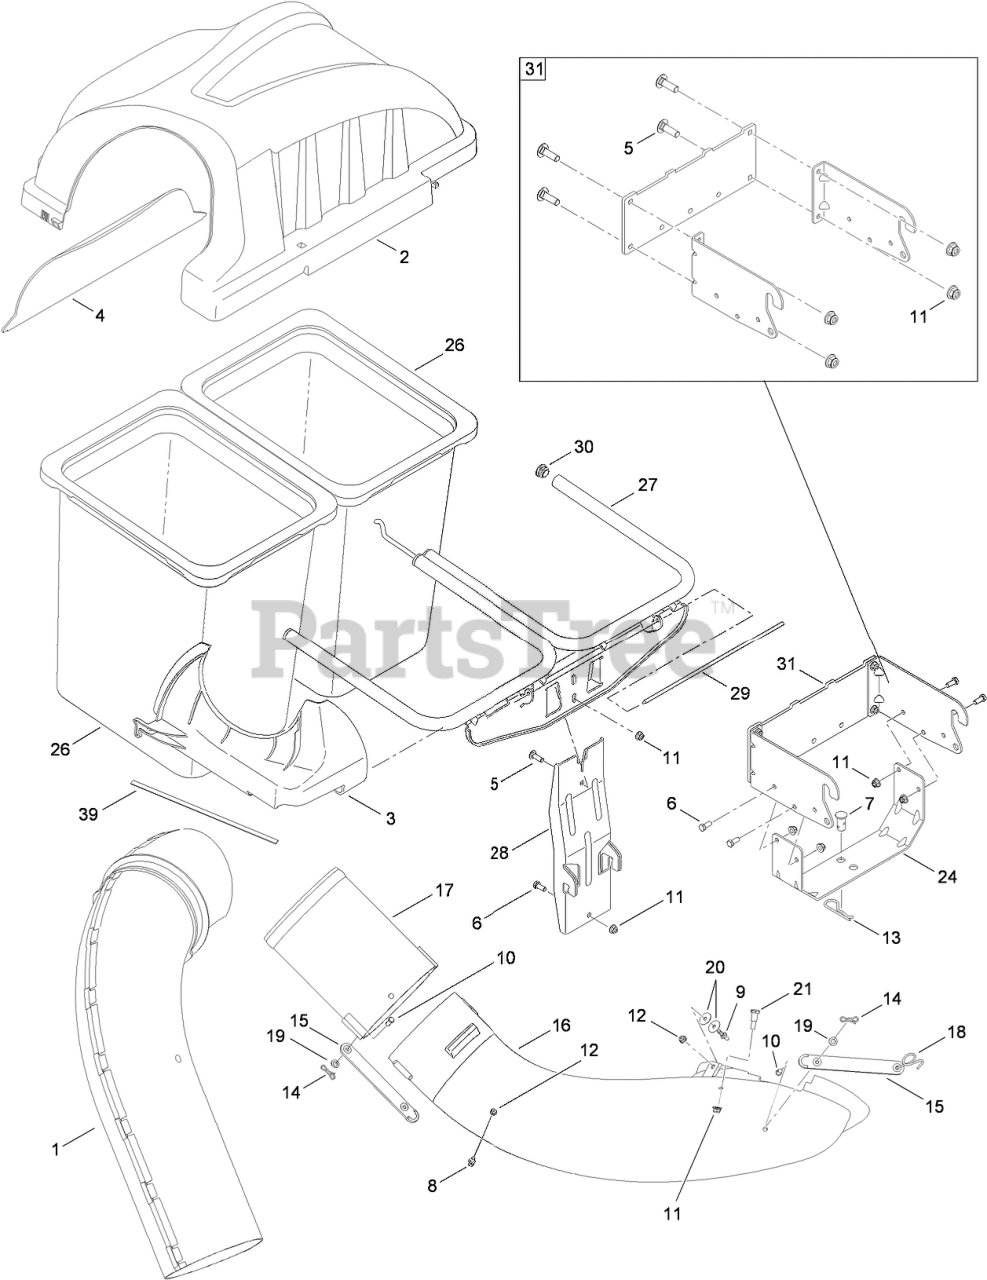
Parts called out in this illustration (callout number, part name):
1	UPPER CHUTE ASM
2	DOUBLE BAGGER COVER ASM
3	SUPPORT-CHUTE, UPPER
4	SCREEN-COVER, BAGGER
5	BOLT-CARR
6	SCREW-HH
7	PIN-CLEVIS
8	PIN-CATCHER, GRASS
9	PIN-ATTACHMENT
10	PIN-CLEVIS
11	NUT-LOCK, FLANGE
12	NUT-LOCK, FLANGE
13	CLIP-HAIRPIN
14	PIN-COTTER
15	STRAP-CHUTE
16	ELBOW-DISCHARGE CHUTE, BAGGER
17	ADAPTER-CHUTE, DISCHARGE
18	HOOK-SPRING, TORSION
19	WASHER-BELL
20	WASHER-FLAT
21	SCREW-SHOULDER
24	SUPPORT-BRACKET, UNIVERSAL
26	GRASS BAG ASM
27	DOUBLE BAG SUPPORT ASM
28	BRACKET-SUPPORT, VERTICAL
29	PIN-HINGE, COVER
30	PLUG-END
31	HITCH BRACKET ASM
39	FOAM STRIP-SELF ADHESIVE
